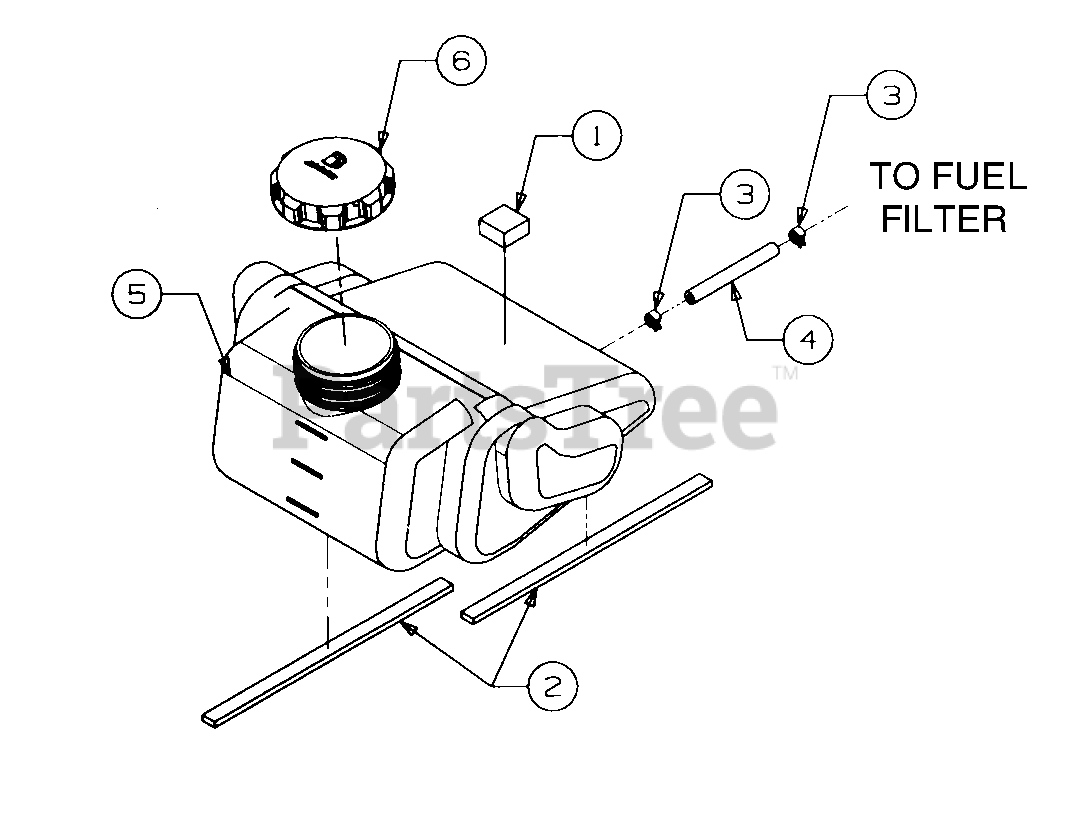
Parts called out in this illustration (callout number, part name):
1	Foam, 1.25 Sq x .62 Thk
2	Tape, Foam, .625 Wide x .25 Thk
3	Clamp, Hose
4	Line,Fuel, 72"
5	Tank, Fuel
6	Cap, Fuel
